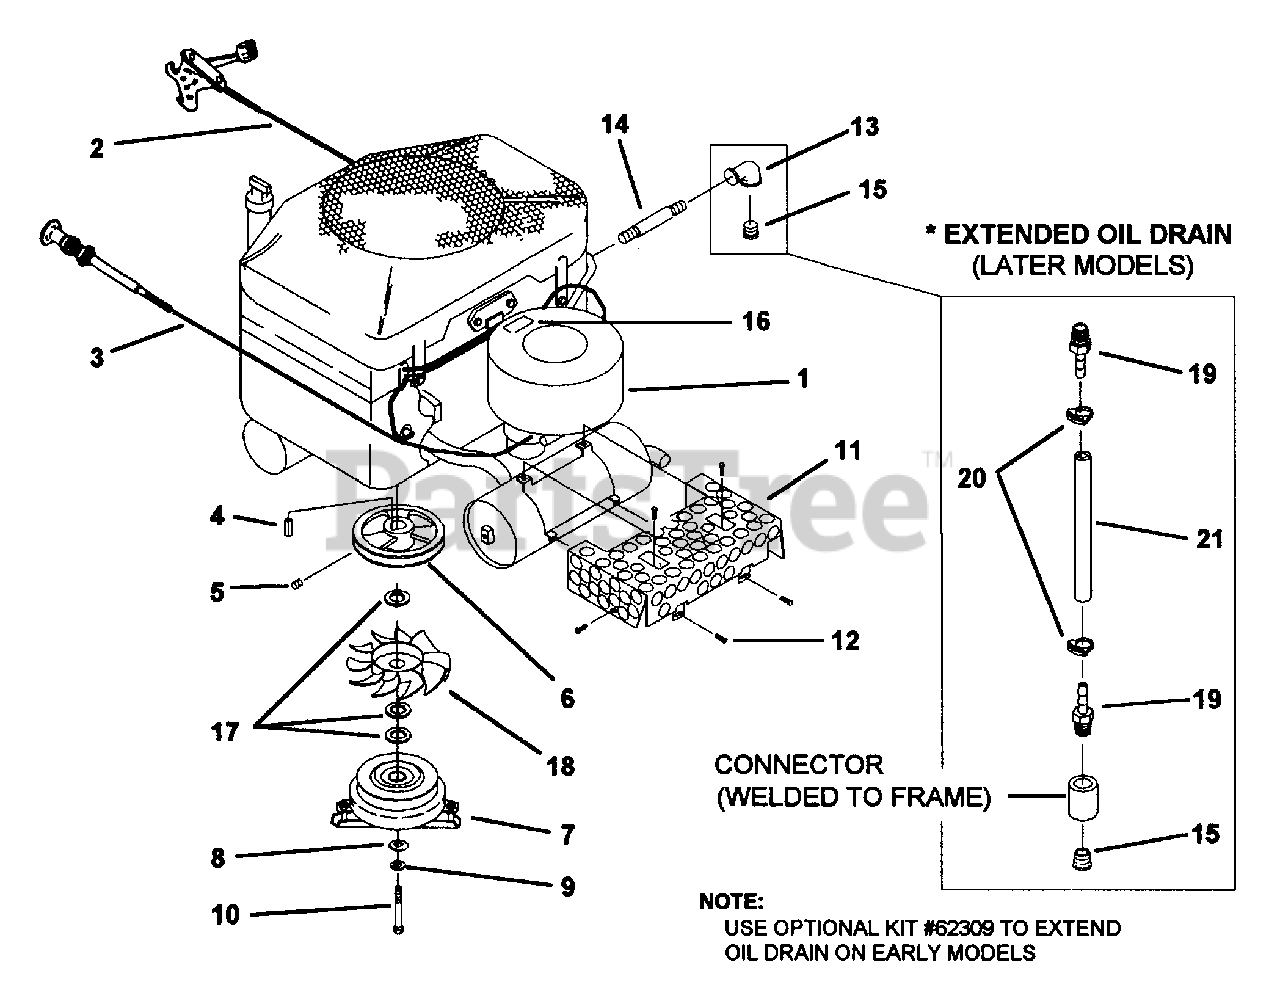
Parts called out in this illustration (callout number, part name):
1	* 18 HP KOHLER, VERTICAL SHAFT ENGINE
2	CABLE, THROTTLE 18 & 20 HP
3	CABLE, CHOKE 18 & 20 HP
4	KEY, SQUARE, 1/4" X 1"
5	SETSCREW, SOCKET HD., 5/16-18 X 3/8"
6	PULLEY, 1" BORE
7	CLUTCH, ELECTRIC, 1"BORE
8	WASHER, 15/32" I.D.
9	LOCKWASHER, 7/16" SPLIT SPRING
10	CAPSCREW, 7/16-20 X 3-1/2" GR. 5
11	MUFFLER GUARD
12	SCREW, SHEET METAL, #8 X 1/2"
13	ELBOW, 3/8, 90D, SCH. 40 CAST IRON
14	NIPPLE, 3/8 X 3" SCH. 40 BLACK
15	PLUG, PIPE 3/8"
16	DECAL, "PERIODICALLY CLEAN"
17	WASHER, SHIM
18	FAN, 7" DIA. 10 BLADE CW
19	HOSE BARB, 3/8" HOSE X 3/8" MPT
20	HOSE CLAMP, 19-32-21/32, NYLON
21	HOSE, 3/8" ID X 6-3/4" LONG
